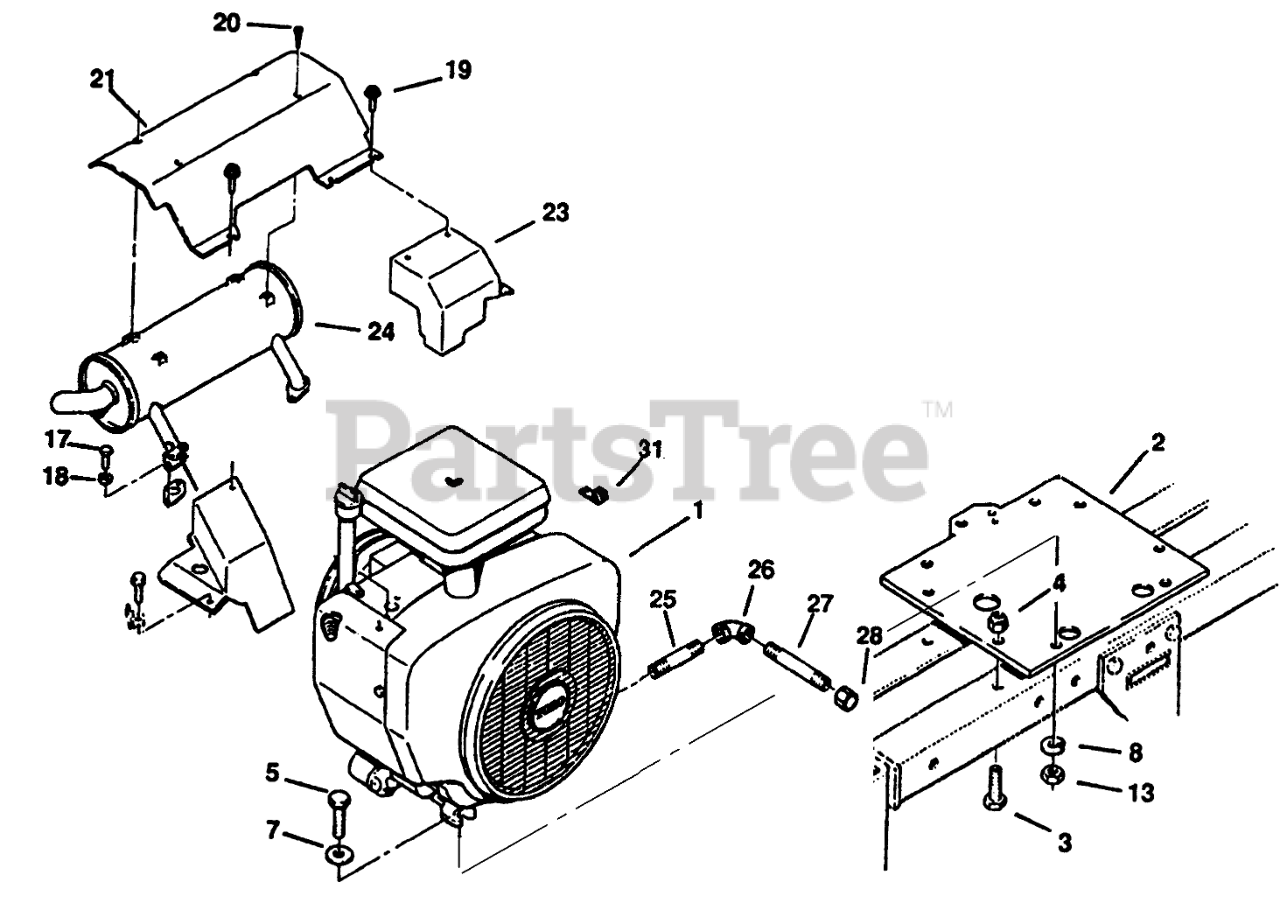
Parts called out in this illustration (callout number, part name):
1	Engine-16HP TORO Power Plus P216G-I/10976D
2	PLATE-ENGINE B
3	Bolt
5	Bolt
7	WASHER-FLAT
8	WASHER-LOCK/SP
13	NUT-HEX
17	SCREW-HH
18	WASHER-LOCK
19	SCREW-HH
20	Screw
21	Air Deflector
22	LH Exhaust Cover
23	RH Exhaust Cover
24	MUFFLER-EXHAUST
25	Pipe
26	ELBOW 3/8 90 DEG
27	PIPE-NIPPLE 3/8 X 4"
28	Cap
30	Exhaust Gasket
31	J-CLIP
